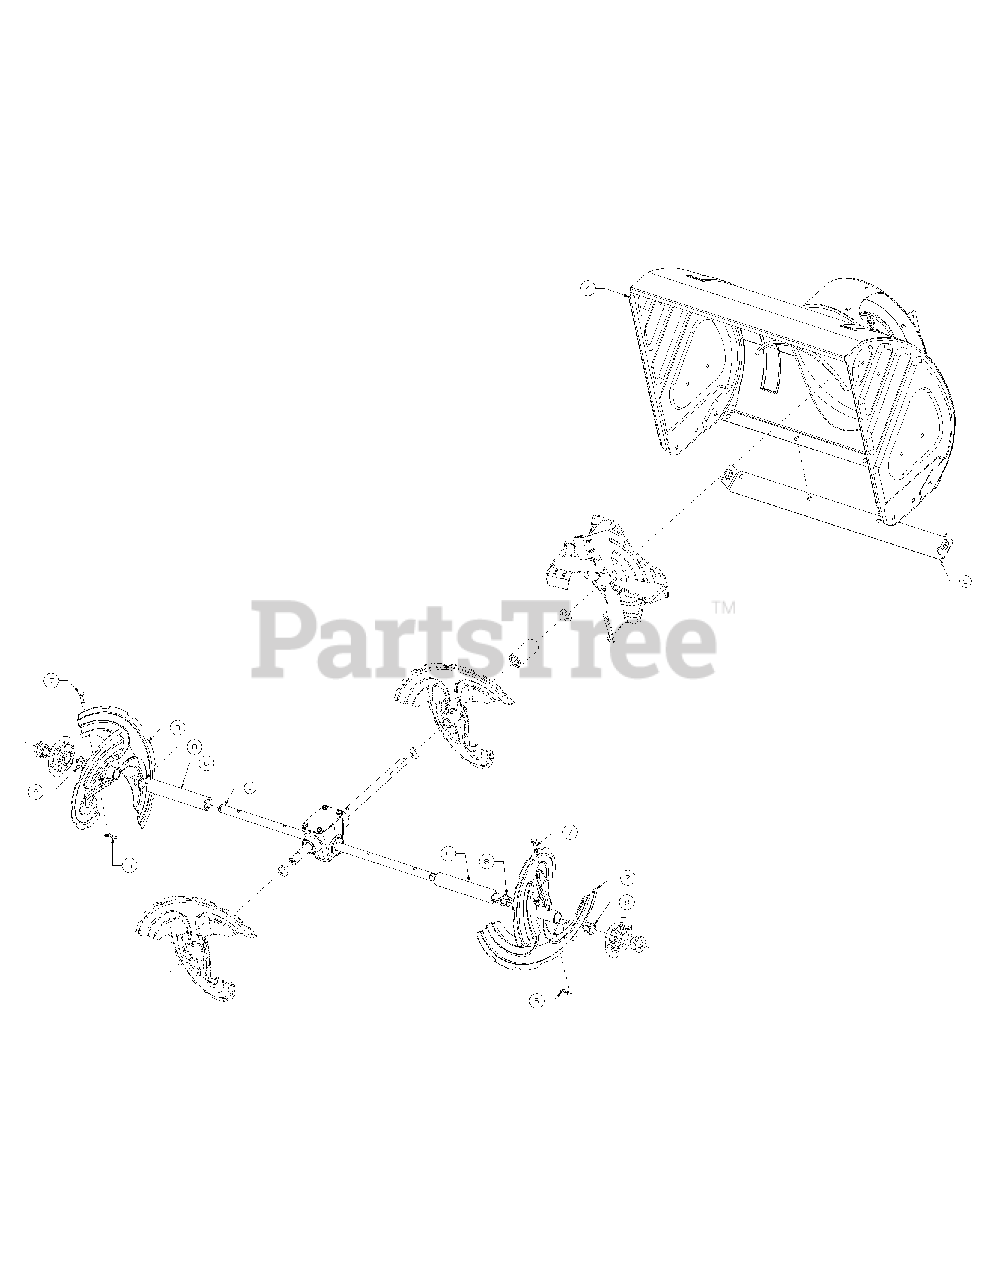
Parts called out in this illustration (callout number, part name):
1	Gearbox Asm-Aug
2	Auger Assembly-LH
3	Auger Assembly-RH
4	Housing-Auger 26"
5	Pin-Cotter
6	Spacer
7	Pin-Shear .25
8	Flange Bearing
9	Plate-Shave 26"
